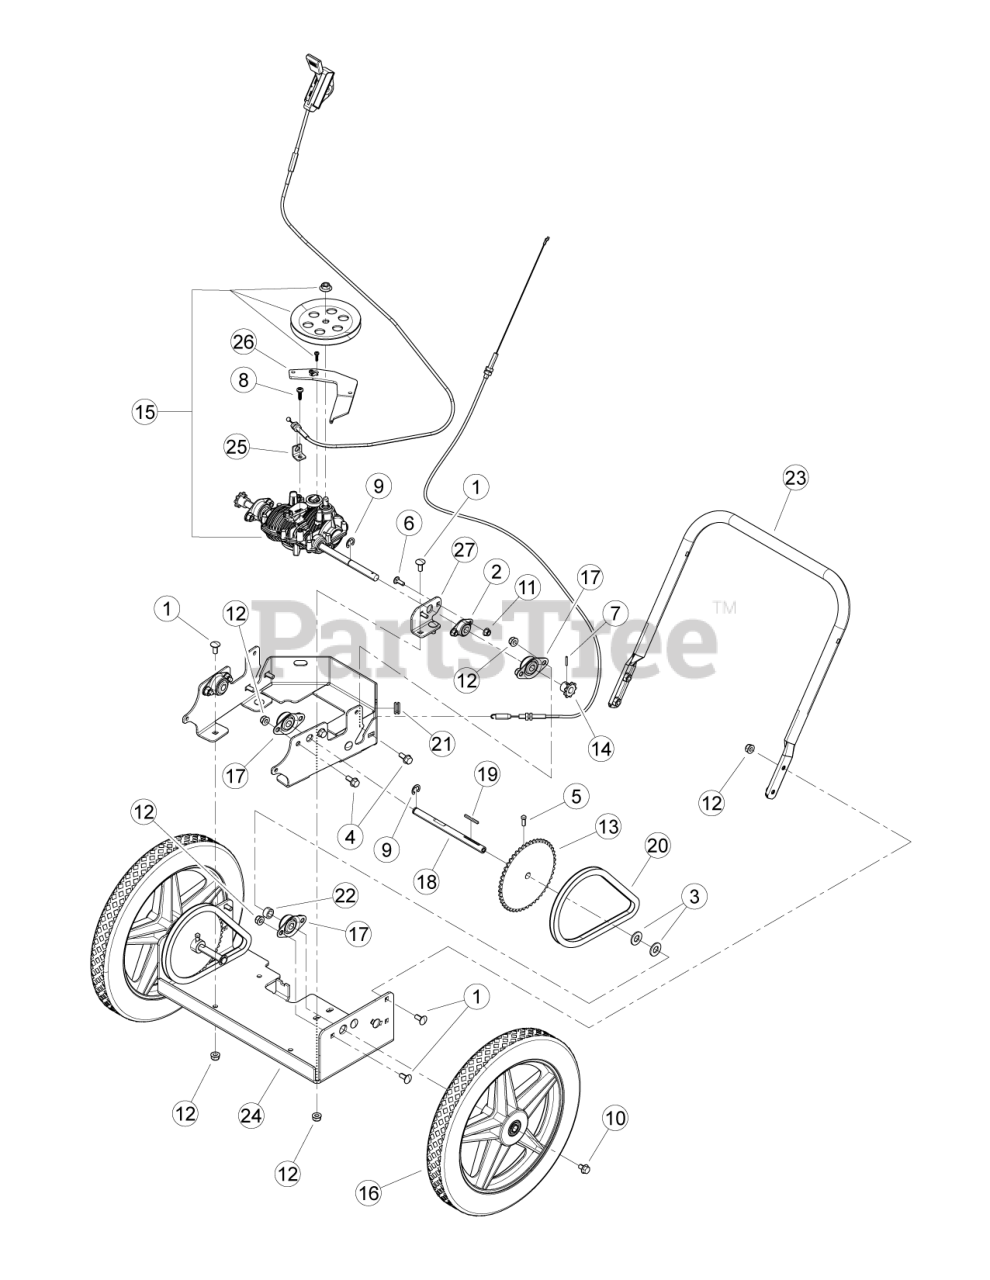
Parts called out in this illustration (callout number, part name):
1	BOLT, 5/16-18 × 3/4 SN GR5 CRG
2	BEARING, 1/2 FLANGE
3	WASHER, 1/2 SAE FLAT
4	BOLT, 5/16 × 3/4 FLANGE NC
5	SCREW, SET 1/4 × 5/8 SQ HD
6	BOLT, 1/4 × 3/4 GR5 CRG ZP
7	PIN, 1/8 × 3/4 IN. SPRING LOCK
8	SCREW, M6 × 1 mm × 20 mm FORMING
9	CLIP, 1/2" E
10	BOLT, 5/16-18 × 1/2 G5 HH SERRATED FLANGE
11	NUT, 1/4-20 NYLOCK-FLANGE
12	NUT, 5/16-18 NYLOCK FLANGE
13	SPROCKET, 35B48T WITH .500 HUB ID
14	SPROCKET, 35B9T WITH .500 HUB ID
15	TRANSMISSION, 3 SPEED MG512
16	WHEEL, TRIMMER HUB 15 × 1.75
17	BUSHING, FLANGE 1/2 DIA 38 DEG MAX ANGLE
18	SHAFT, WT AXLE
19	KEY, 1/8 × 1/8 × 1-3/8
20	CHAIN, #35 × 60 PITCH W/ C LINK
21	GROMMET, 3/8 ID PUSH IN
22	SPACER, .75 OD × .5 ID × .37
23	HANDLE BAR, LOWER TRIMMER PAINTED
24	BRACKET, WT BASE
25	BRACKET, TRANS SPEED CABLE
26	LEVER, WT TRANS ENGAGE SS
27	BRACKET, TRANS SHAFT SUPPORT
